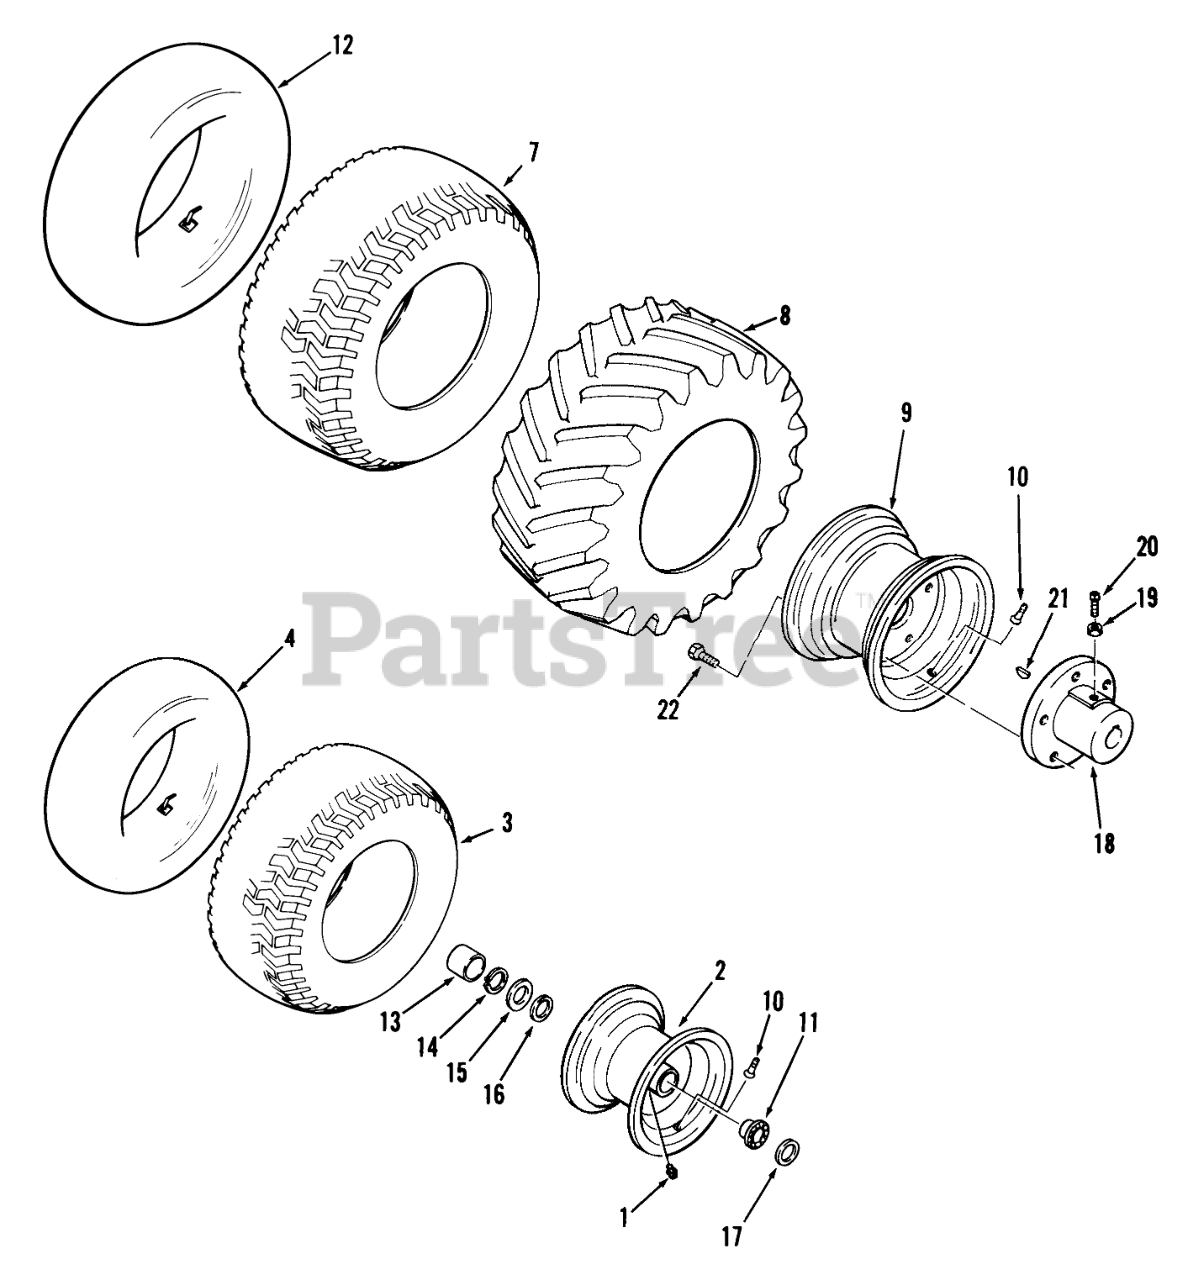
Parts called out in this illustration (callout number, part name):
1	Zerk
2	WHEEL ASSY
3	TIRE TURF SAVER 16X6.50-8
4	TUBE-INNER
7	Tire
8	Tire-Cleat, Rear
9	Wheel
10	VALVE
11	Ball Bearing
12	TUBE-INNER
13	HUB CAP
14	Snap Ring
15	Washer
16	WASHER
17	WASHER-SHIM
18	Hub Rear
19	Nut
20	Screw-Set
21	KEY-WOODRUFF
22	Lug Nut
